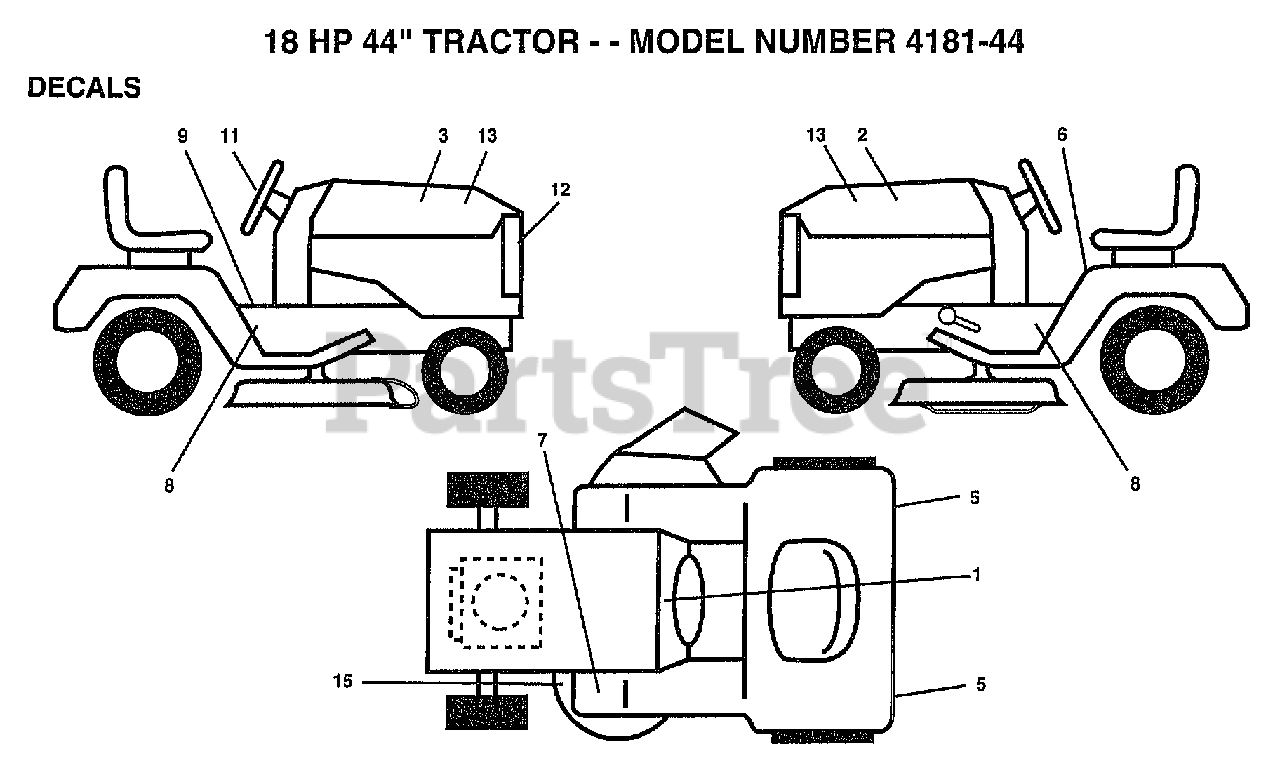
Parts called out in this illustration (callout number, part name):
1	DECAL.DASH.INST.
2	HOOD DECAL LH
5	REFLECTOR-TAIL YT
6	DECAL
9	DECAL BRAK PARK
12	GRILL DECAL
13	NAMEPLATE LOGO
15	"DECAL.V.BELT.44"""
